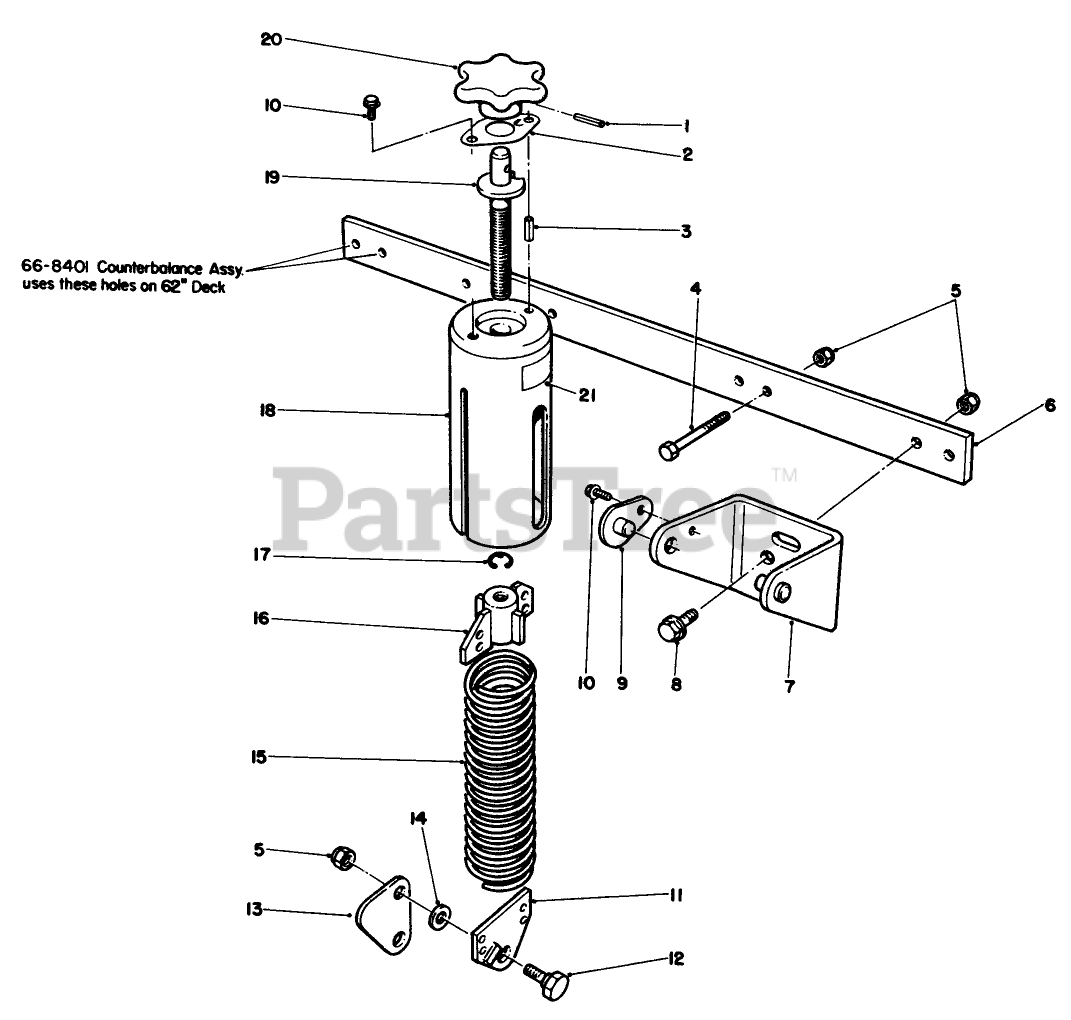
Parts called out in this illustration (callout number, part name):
1	PIN-ROLL
2	DETENT SPRING
3	ROLL PIN
4	SCREW-HH
5	NUT-LOCK, NI
6	Adapter
7	MOUNTING BRACKET WA R
8	SCREW-HHF
9	LOCK PIN WA
10	SCREW
11	End Spring
12	BOLT-SHOULDER
13	Link
14	WASHER-FLAT
15	Spring-Extension
16	SPRING END WA (NO FINISH)
17	RING-RETAINING, EXTERNAL
18	COVER ASSEMBLY
19	SHAFT WA
20	KNOB (MACHINED) R
21	DECAL-WARNING
